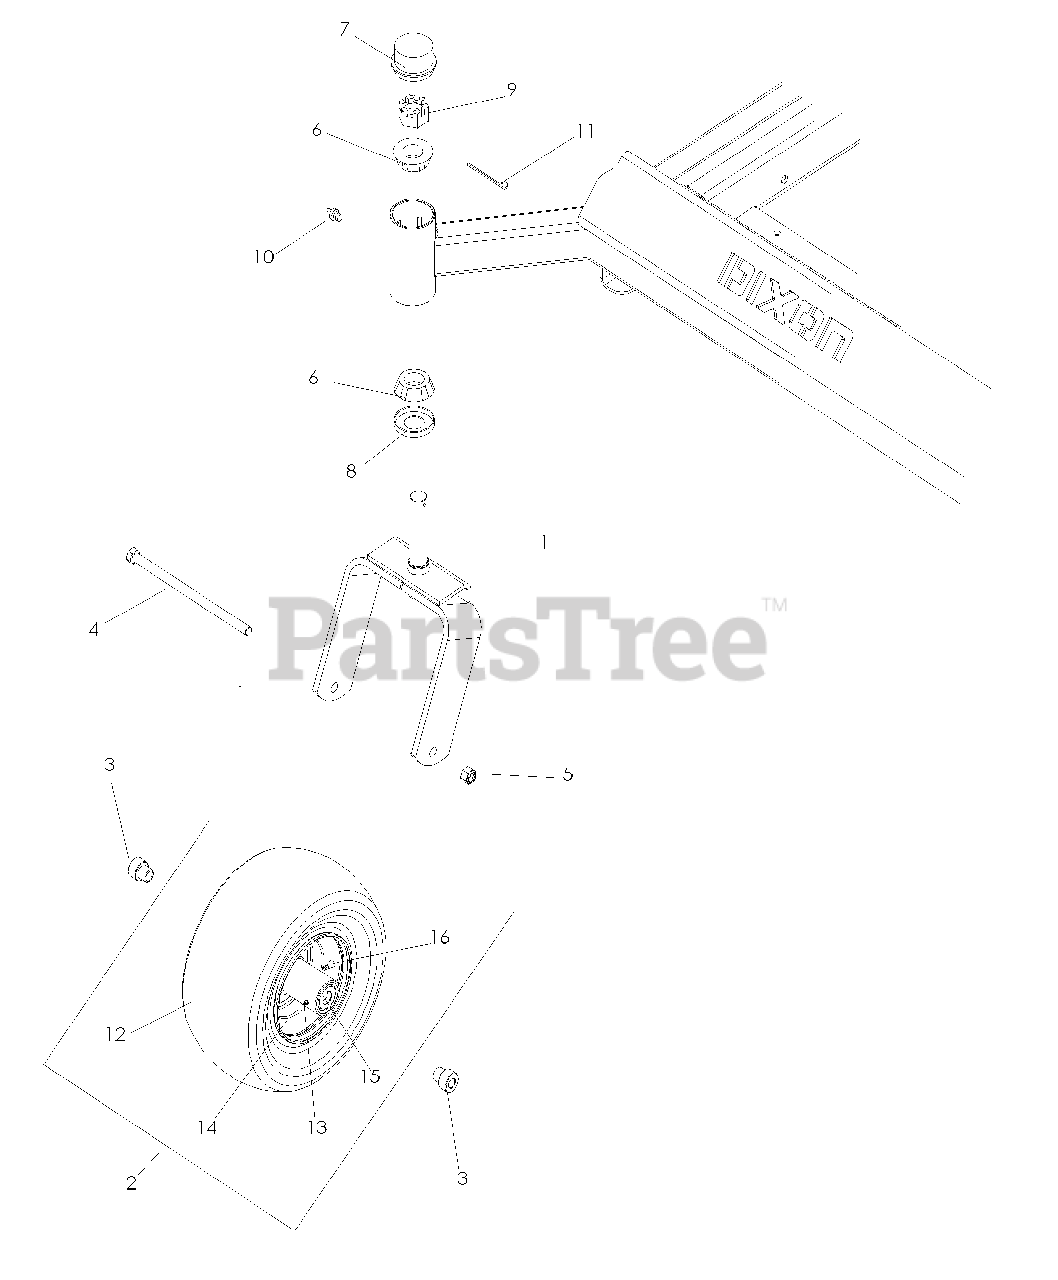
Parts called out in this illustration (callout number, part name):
1	YOKE, CASTER, BLUE
2	FRONT TIRE ASSY
3	AXLE SPACER
4	HEX SCREW 1/2-13 X 9.5 GR5
5	NUT 1/2-13 HEX NYLOC ZD
6	TAPERED ROLLER BRG
7	GREASE CAP
9	NUT 1"C HEX SLOTTED
11	COTTER PIN 1/8 X 2
12	TIRE - SMOOTH 13X6.50-6
13	ZERK
16	VALVE STEM TR-412
